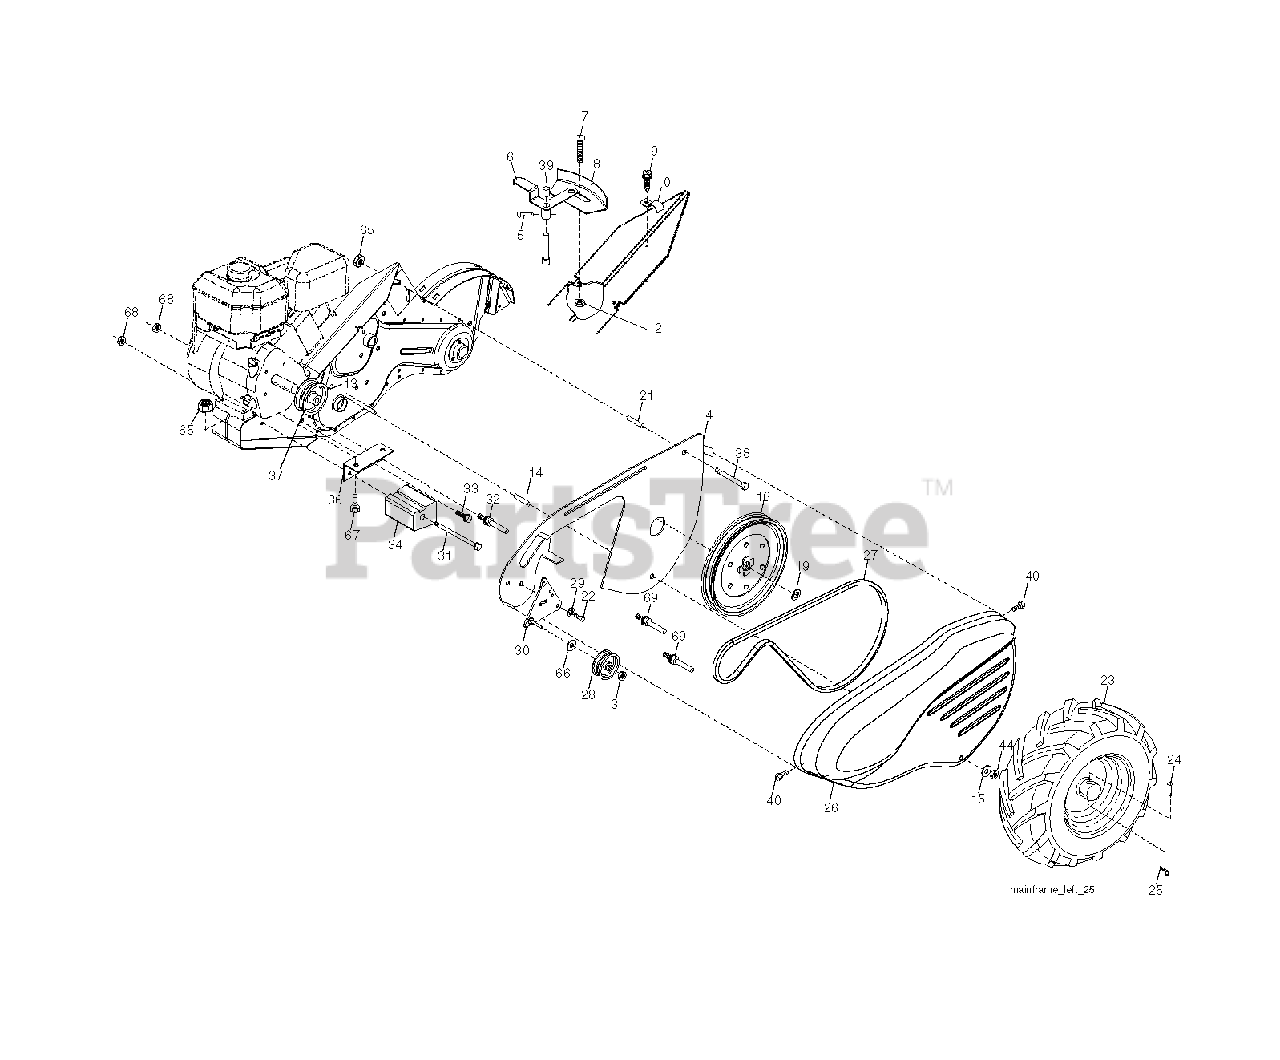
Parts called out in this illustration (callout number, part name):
3	LOCKNUT
4	SHIELD.INNER.BELT.GUARD.RT
5	PIN.SPIROL.FLARED
6	LEVER ASM CRT
9	TAPPING SCREW
10	CONDUIT CLIP T
12	NUT
15	WASHER
16	SHEAVE, TRANSMISSION
19	RETAINING RING LT
21	SPACER-SPLIT.327 X .42
24	RIVET,DRILLED
25	RETAINER M
27	V-BELT
28	PULLEY-IDLER TI
30	BRACKET.ASM.IDLER
31	BOLT.FIN.HEX.3/8-16UNC
32	SHIFT ARM CRT
33	BOLT
34	COUNTERWEIGHT.LH.CRT
36	BRACKET LH CRT
37	ENGINE PULLEY
38	BOLT
39	CAP.PLUNGER.BLACK
40	SCREW.HEX.WSH.SLT.#10-24X.50
44	NUT.71038.31-18.HEX.NYLOCK
65	LOCKNUT-FLANGE 5/16-18
66	WASHER
67	BOLT
69	KEEPER.BELT.ENGINE
